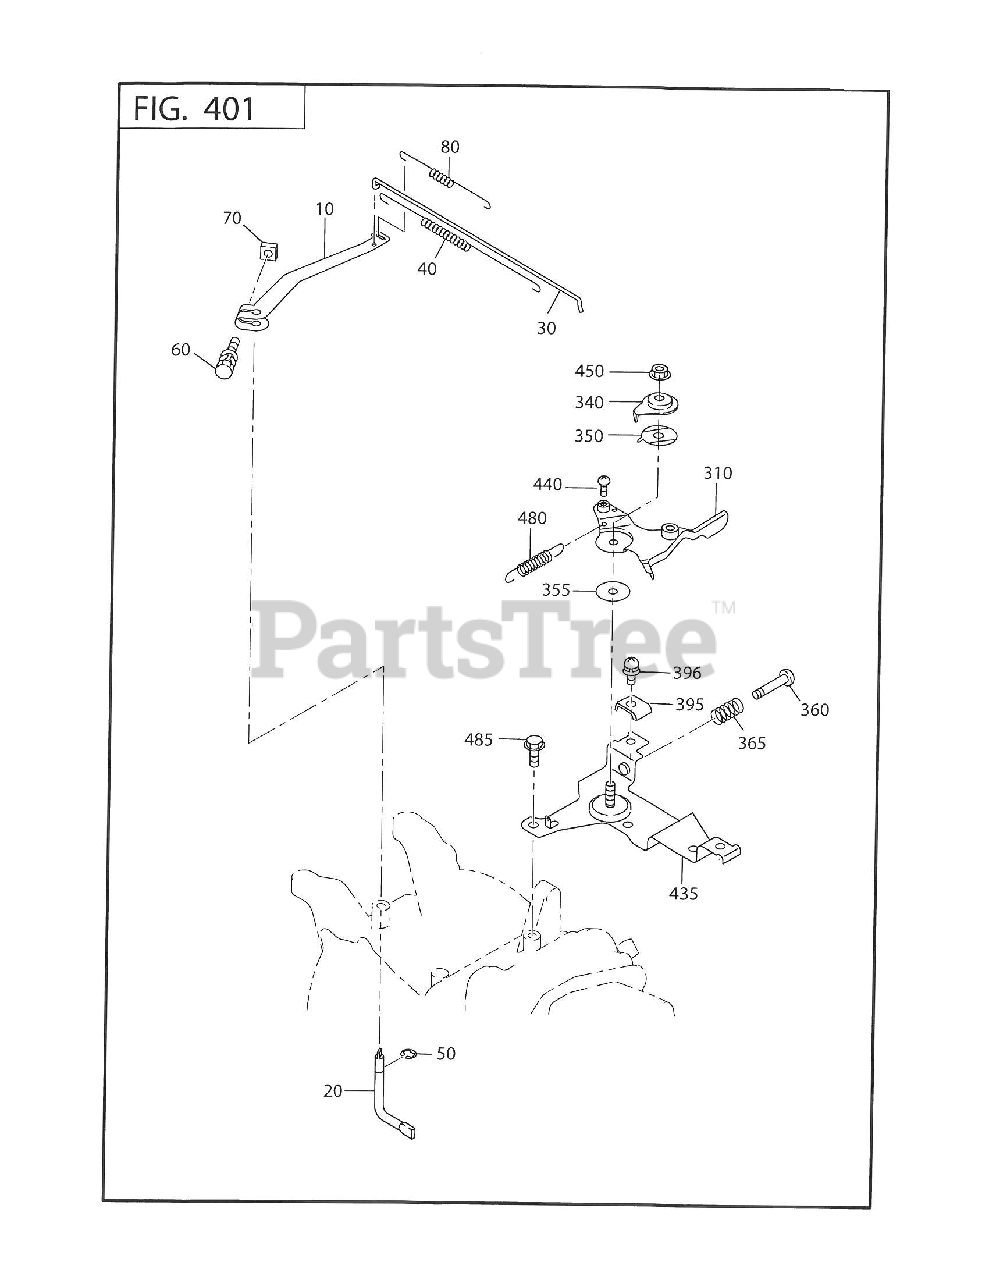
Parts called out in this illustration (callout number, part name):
310	CONNECTING ROD AY
311	CONNECTING ROD AY
320	CONNECTING ROD BOLT
370	PISTON RING SET
371	PISTON RING SET
372	PISTON RING SET
